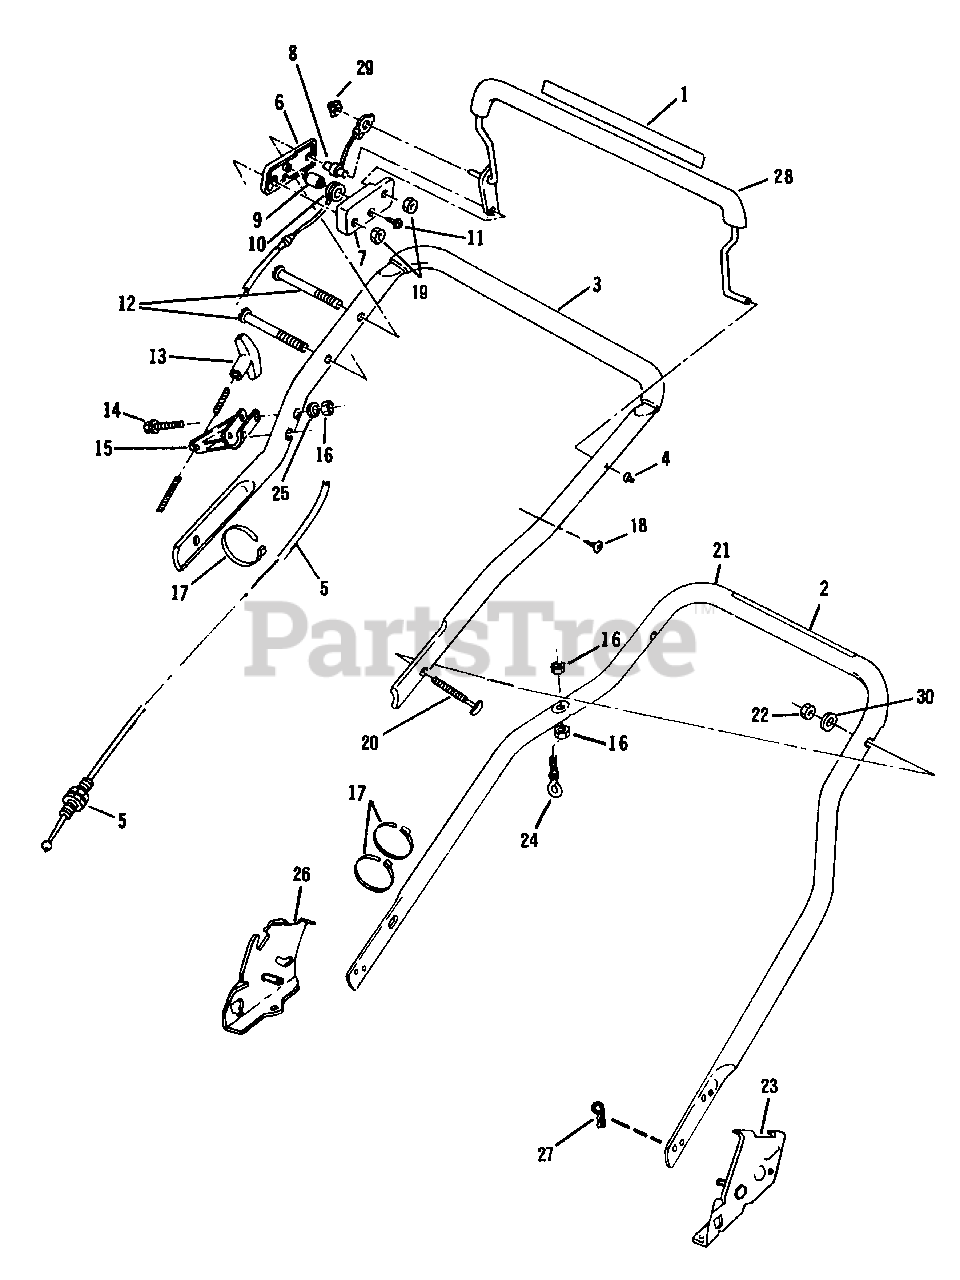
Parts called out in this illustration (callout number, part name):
1	Decal-Eng./Blade Control
2	Decal-Starting Inst.
3	Top Handle
4	Pushnut
5	Control Cable Assembly
6	Control Case-Outer
7	Control Case-Inner
8	Column
9	Pin
10	Pulley
11	Screw
12	Screw
13	Handle-Starter
14	Screw-Truss Head
15	Rope Guide Assembly
16	Locknut
17	Tie Strap
18	Screw
19	Nut-Hex-Centerlock
20	Screw
21	Handle-Bottom
22	Nut
23	Bracket-Handle-L.H.
24	Eyebolt
25	Washer
26	Bracket-Handle-R.H.
27	Hair Pin-Handle Bracket
28	Control Lever and Nut Assem.
29	Nut-Acorn
30	Washer
